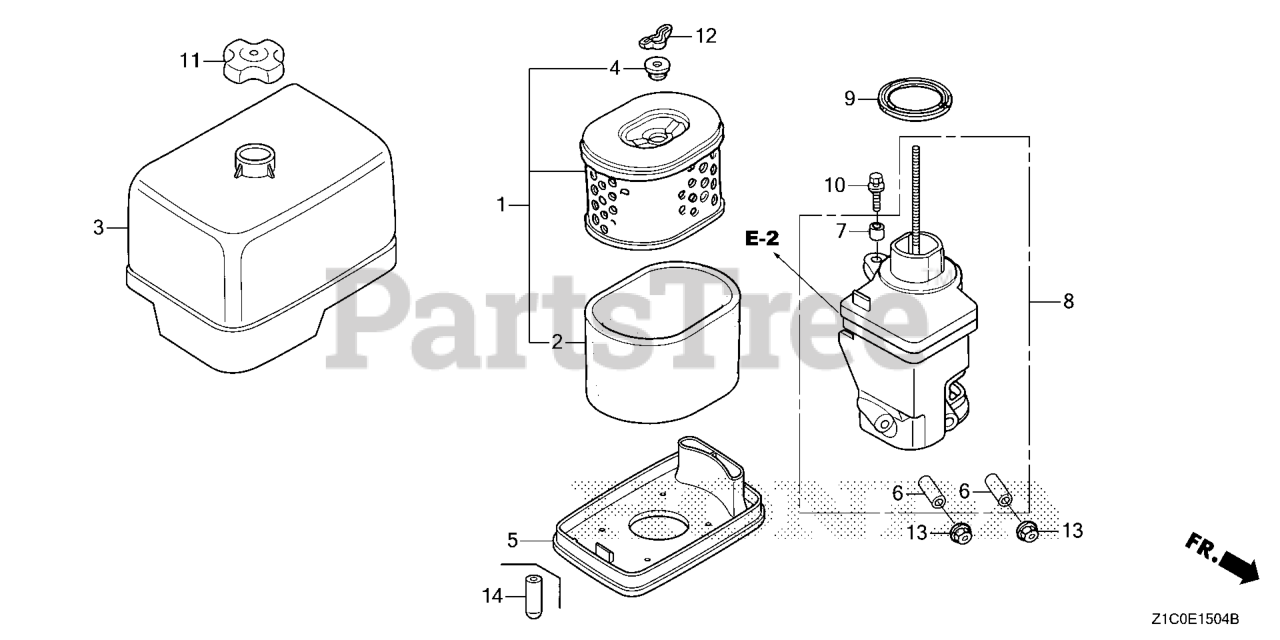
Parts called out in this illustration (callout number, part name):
1	ELEMENT, AIR CLEANER
2	FILTER (OUTER)
3	COVER, AIR CLEANER HOUSING
4	GROMMET, AIR CLEANER
5	NOSE, MUFFLER
6	COLLAR, AIR CLEANER
7	COLLAR B, AIR CLEANER
8	ELBOW, AIR CLEANER
9	GASKET, AIR CLEANER HOUSING
10	BOLT-WASHER (6X22)
11	NUT, AIR CLEANER COVER
12	WINGNUT, TOOL BOX SETTING
13	NUT, FLANGE (6MM)
